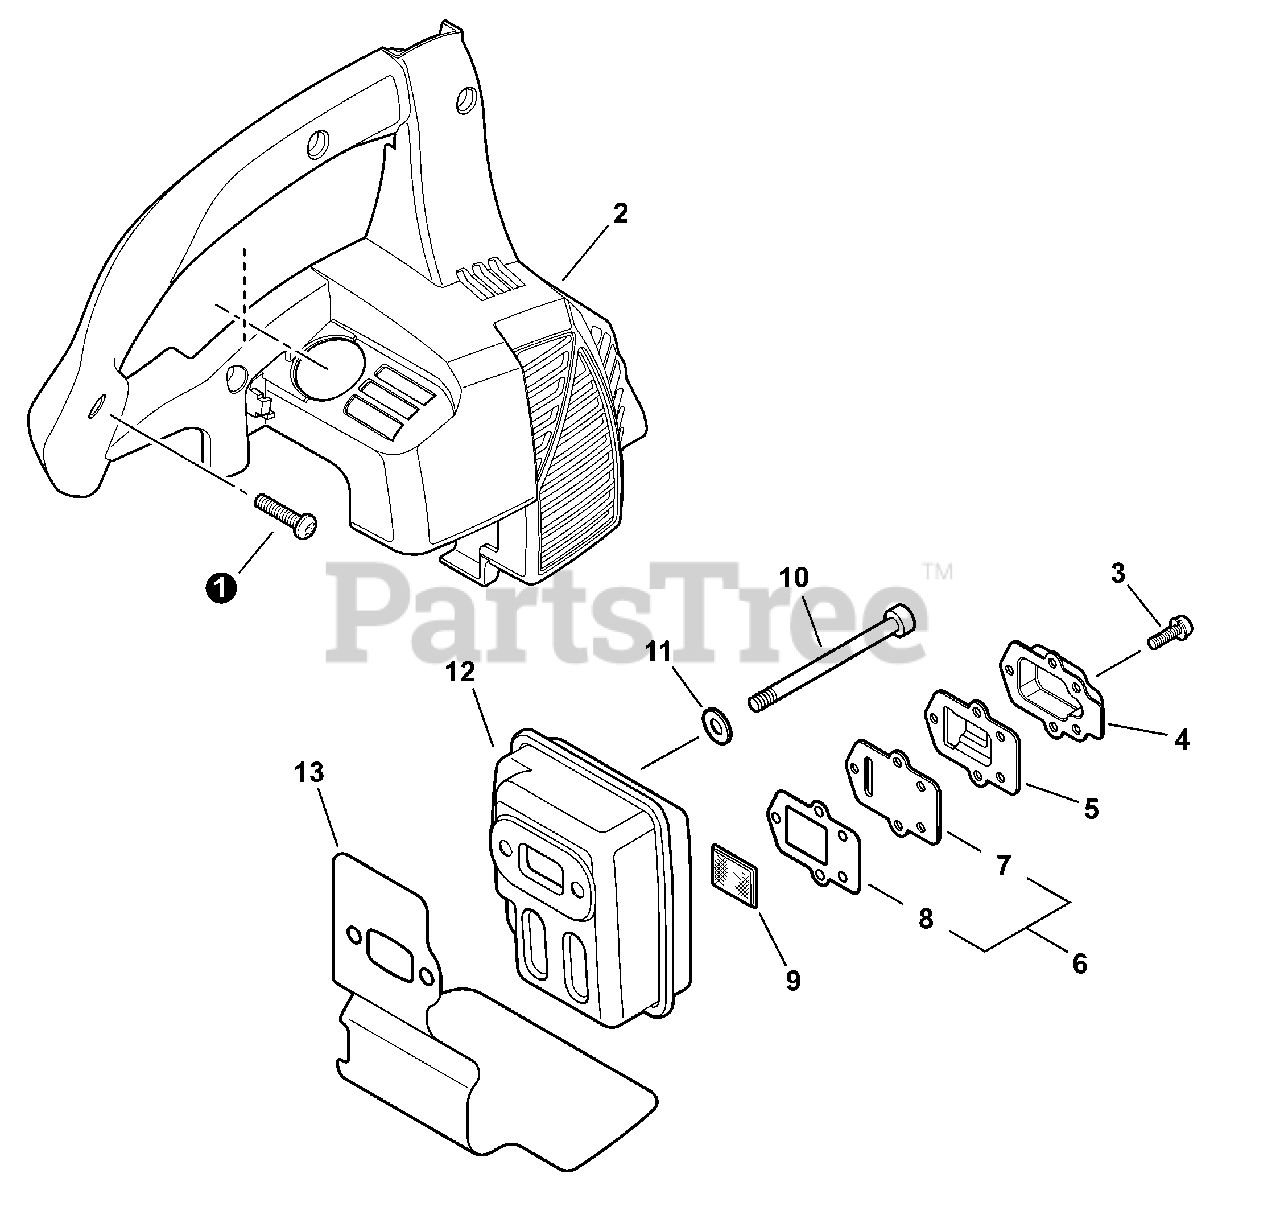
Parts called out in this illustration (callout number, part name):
1	SCREW - 5×20
2	COVER, ENGINE
3	SCREW - 4×8 -- TORX
4	GUIDE, EXHAUST - OUTER
5	GUIDE, EXHAUST - INNER
6	EXHAUST GUIDE KIT
7	GUIDE, EXHAUST
8	GASKET, EXHAUST
9	SCREEN, SPARK ARRESTER
10	BOLT - 5
11	WASHER - 5
12	MUFFLER
13	SHIELD, EXHAUST
